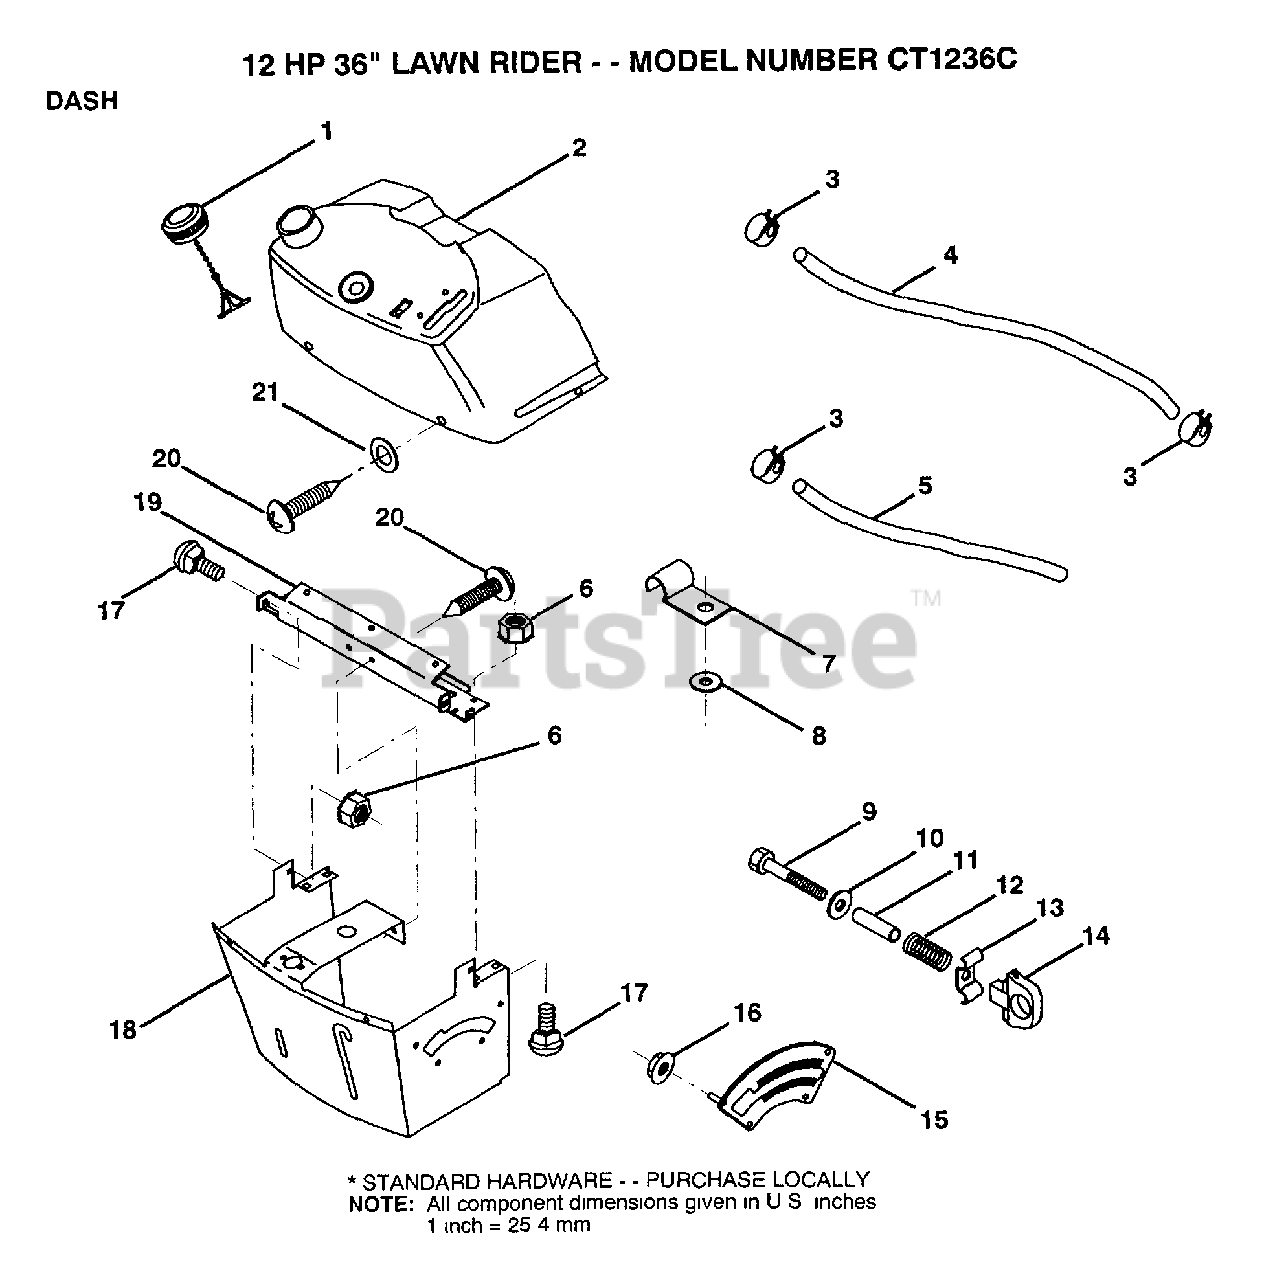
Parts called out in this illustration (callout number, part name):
3	HOSE CLAMP
5	FUEL LINE T
6	NUT
7	CLIP T
8	WASHER PM
9	BOLT
11	SPACER SPLIT
12	SPRING M
13	"KNOB,HGT RETAINER"
14	KNOB
15	ADJUSTER QUAD
16	NUT
17	BOLT
18	SUPT ASSY DASH
